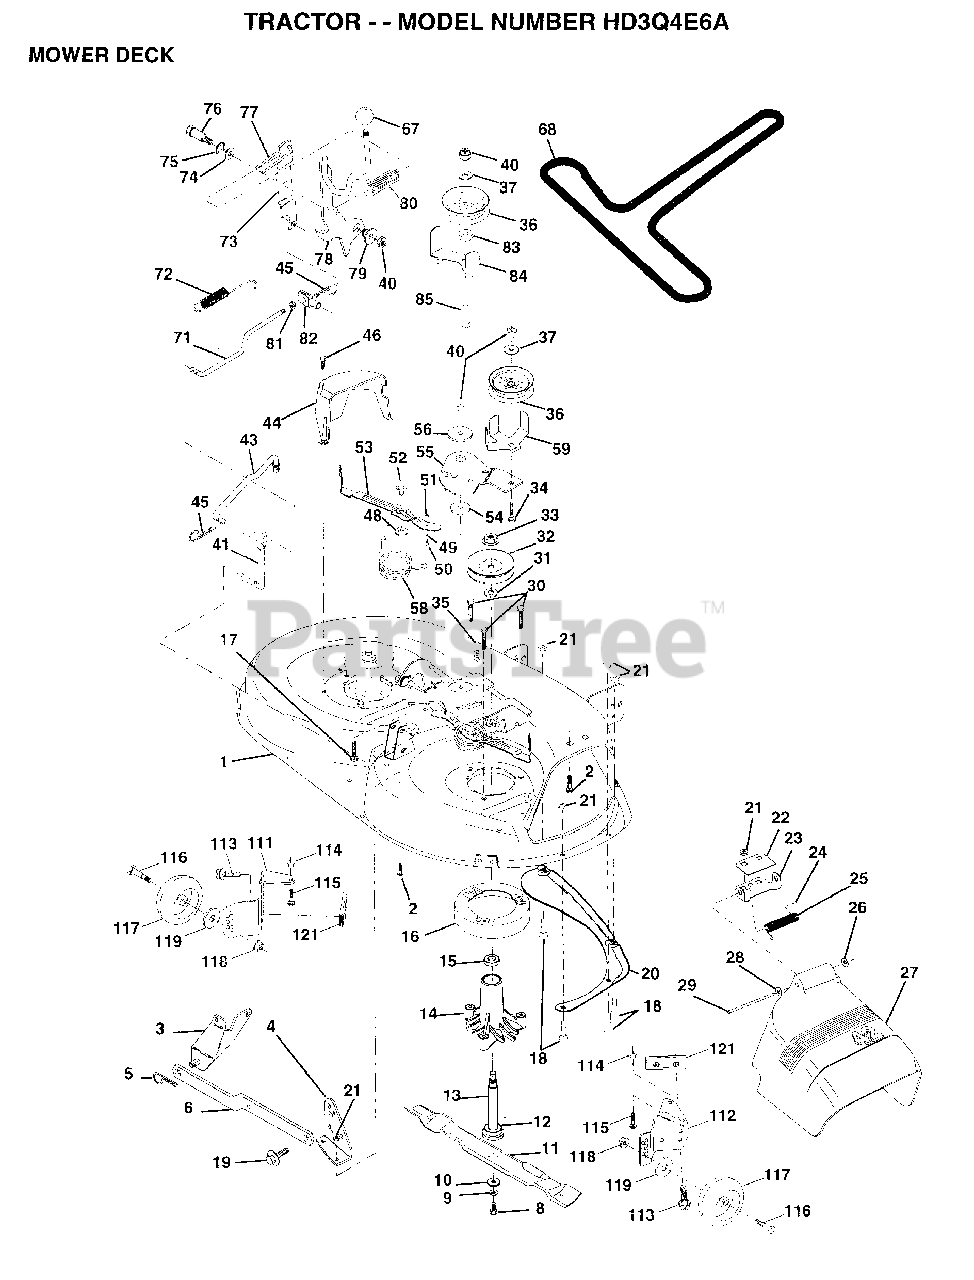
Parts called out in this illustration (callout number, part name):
1	DECK.WELD.42.
2	BOLT
3	BRKT ASM SWAY BAR
4	BRKT DECK SW BAR
8	BLADE BOLT
10	WASHER.HARD.BLADE
11	"BLADE.42"" HIPERF"
12	BEARING.BALL
14	HSG ASM MANDREL
15	BEARING
16	STRIPPER RND MWR
17	BOLT RDHD 3/8-16
18	BOLT
19	BOLT SHD 5/16-18
22	STIFFENER BRKT
23	DEFLECTOR BRKT
24	CAP-SLEEVE LT
25	SPRING TORSION
26	NUT PUSH M
27	DEFLECTOR.SHIELD
28	WASHER
29	HINGE ROD
31	WASHER
34	BOLT
35	XMAS TREE FASTNER
36	FLAT IDLER PULLEY
37	WASHER
41	PIVOT ROD
43	ROD CLUTCH W/NIBS
44	GUARD MAND LH BLK
45	RETAINER M
46	SCREW.1/4-20X5/8
48	HARD SMALL WASHER
50	SHOULDER BOLT
51	LOCKNUT
52	BOLT.SHLD.5/16-18
53	BRAKE PAD ARM ASM
54	HARDENED WASHER
56	SPACER RETAINER
58	SPRING TORSN BRAK
59	GUARD IDLER TUV
67	KNOB T (1/2-HOLE)
68	BELT.V.T-PATH
71	ROD CLUTCH 38/42
72	RETURN SPRING
73	CLUTCH ARM SECOND
74	WASHER
75	RING
76	SHOULDER BOLT
77	SPRING KEEPER
78	LEVER ASM CLT PRM
79	BUSHING
81	NUT
82	TRUNION ADJ
83	WASHER
85	BOLT RDHD 3/8-16
113	SCREW
116	BOLT.SHOULDER
117	WHEEL.GUAGE.MED.
118	LOCKNUT
119	WASHER
121	MANDREL ASM
